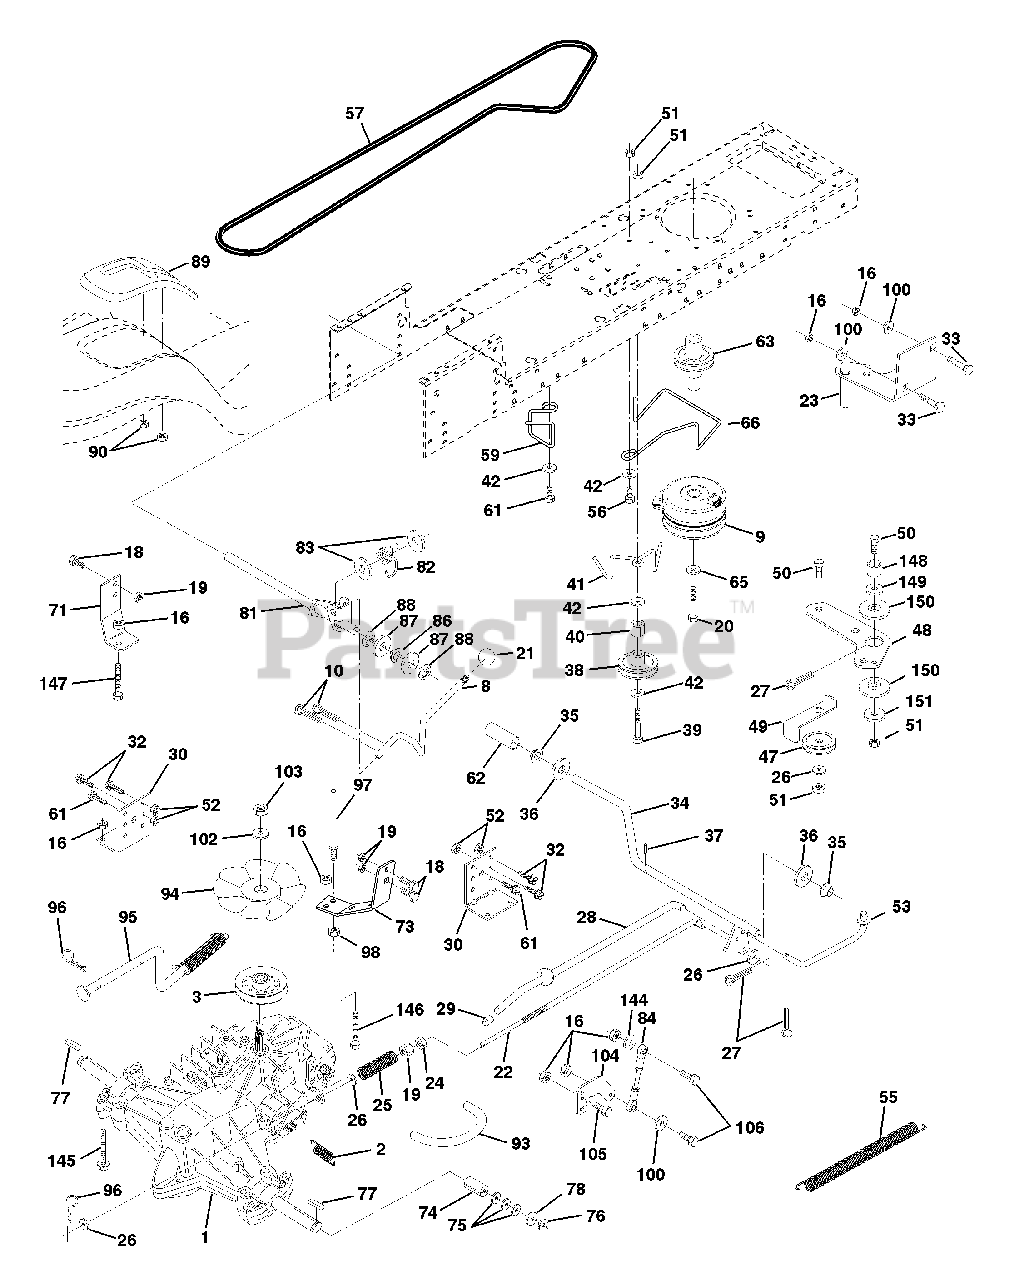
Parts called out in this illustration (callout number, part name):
1	Transaxle w/cas Hydro 310-0650
2	Spring, Return, Brake
3	Pulley, Transaxle Hydro 750 LT
8	Rod Shift STLT
9	Clutch Electric
10	Pin Cotter 1/8 x 1 CAD
15	Bolt Hex 5/16-18 Unc Flghd
16	Nut Lock Hex W/Ins. 5/16-18 Unc P
18	Bolt Fin Hex 3/8-16 Unc x 1 Gr.5
19	Nut Lock Hex W/Ins 3/8-16 Unc
20	Bolt, Hex 7/16-20 x 4-1/4 Ga. 5
21	Knob Deluxe 1/2-13 UNC BLK/BLK
22	Rod, Brake Hydro
23	Bracket Asm Mtg CL
24	Nut Hex Jam 3/8-16 UNC
25	Spring, Brake Rod
26	Washer
27	Pin Cotter 1/8 x 3/4 CAD.
28	Rod, Parking Brake
29	Cap,Parking Brake
30	Bracket, Transaxle
32	Bolt Hex Hd 5/16-18 Unc x 3/4
33	Bolt Carriage 5/16-18 UNC x 3/4
34	Shaft, Foot Pedal
35	Bearing, Nylon
37	Pin, Roll
38	Pulley, Idler, Flat
40	Spacer Split
41	Keeper, Belt Idler
42	Washer 13/32 x 13/16 x 12 Ga
43	Washer 11/32 x 5/8 x 12 Ga.
47	Pulley, Idler, V-Groove Plastic
48	Bellcrank Clutch Grnd Drv Stl
49	Retainer, Belt Style Spring
50	Bolt
52	Nut Crown Lock 5/16-18
53	Link, Clutch
55	Spring, Return, Clutch
56	Bolt, Fin Hex 3/8-16 UNC x 1 1/4
57	V-Belt, Ground Drive
59	Keeper, Center Span
61	Screw Thdrol. 3/8-16 x 3/4 Ty. TT
62	Cover, Pedal Premium
63	Pulley, Engine
65	Washer Lock Hvy HLCL Spr 7/16
66	Keeper Belt Engine
71	Strap Torque Lh Hydro 18/20" T
73	Strap Torque Rh Hydro 0650
74	Spacer, Split
75	Washer 25/32 x 1-1/4 x 16 Ga.
77	Key, Square
78	Washer 25/32 x 1-5/8 x 16 Ga
81	Shaft Asm. Cross Hydro 20" Tires
82	Spring Torsion T/A
83	Washer 17/32 x 3/4 x 16 Ga.
84	Rod, Tie Hydro 20" Tires SPH Ball 4.75
86	Bushing Rod Strig. 629/632 ID
87	Washer 21/32 x 1-1/4 x 16 Ga.
88	Ring Klip #5304-62
89	Console, Hydro
90	Nut Self-Thd Wsh-Hd 1/4 Zinc
91	Bolt Fin Hex 5/16-18 x 2-1/4
92	Bolt Fin Hex 5/16-18 Unc x 1-1/2
93	Line Fuel Hydro 4"
94	Fan, Hydro 7"
95	Control Asm. Bypass Hydro
96	Retainer Spring 1" Zinc/Cad
97	Keeper Belt Rh Hydro 0750.18/20"
98	Nut Keps Hex 3/8-16 Unc
100	Washer 11/32 x 3/4 x 16 Ga.
102	Washer Belleville .501D x 1.50D
103	Nut Hex Jam Toplock 1/4-20 Unf
104	Arm, Control Hydro
105	Screw Cap Hex 5/16 x 18 x 1
106	Bolt Fin Hex 5/16-18 Unc x 1-1/4
144	Washer 11/32 x 5/8 x 16 Ga.
146	Bolt Hex Flghd 5/16-18 x 2-1/4
147	Bolt Hex Flghd 5/16-18 x 1-1/2
149	Spacer Retainer PM Mower
150	Bushing Nylon Collered
151	Washer 13/32 x 2 x 10 Ga.
